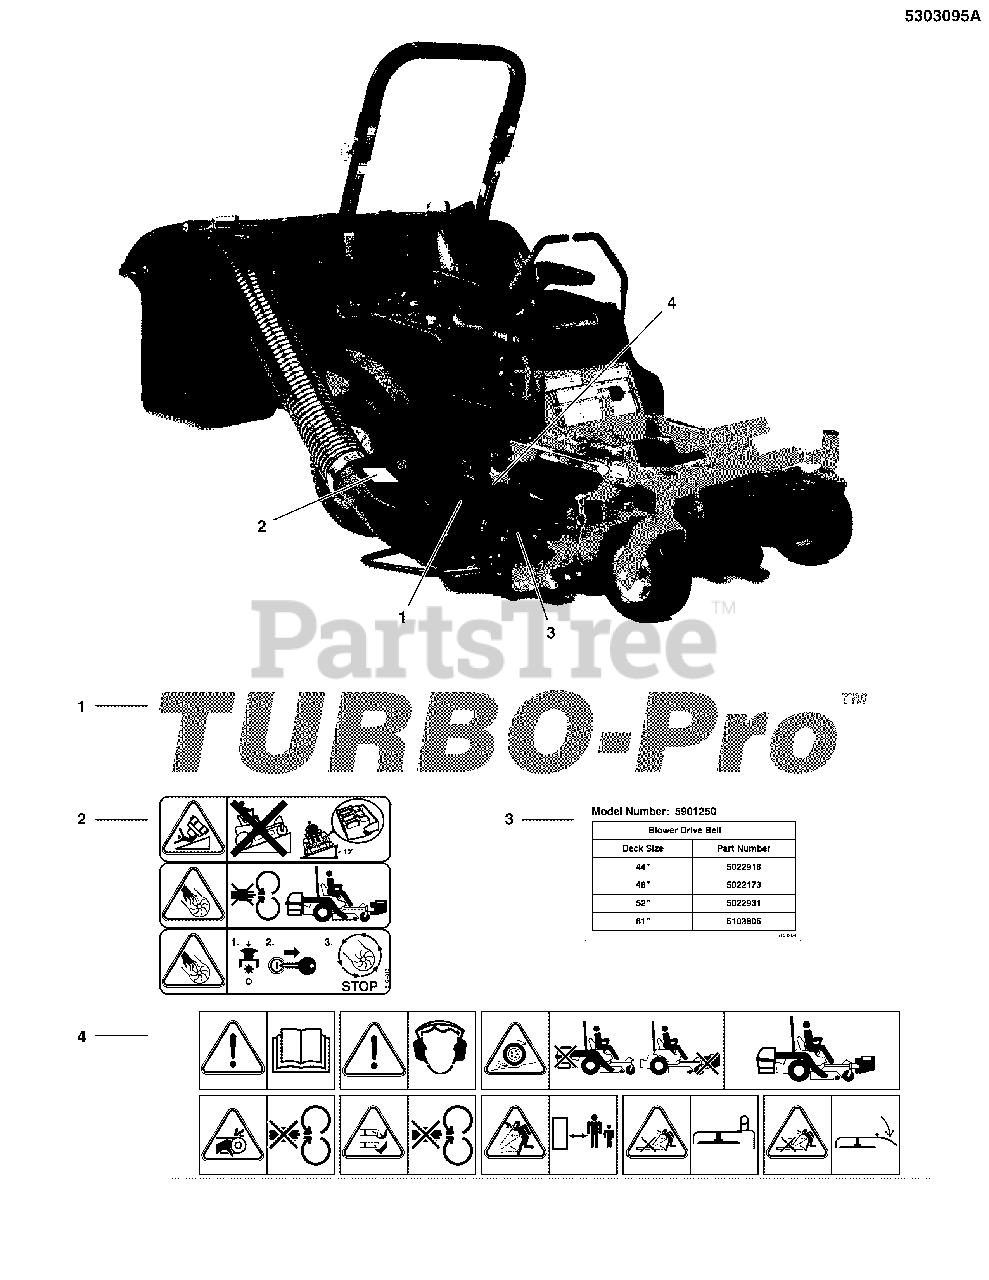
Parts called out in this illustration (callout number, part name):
1	DECAL, TURBO-PRO
2	DECAL, BLOWER, SMALL, ICONS
3	DECAL, BELT, TURBO-PRO, ALL
4	DECAL, BLOWER, MAIN, LARGE, ICONS
